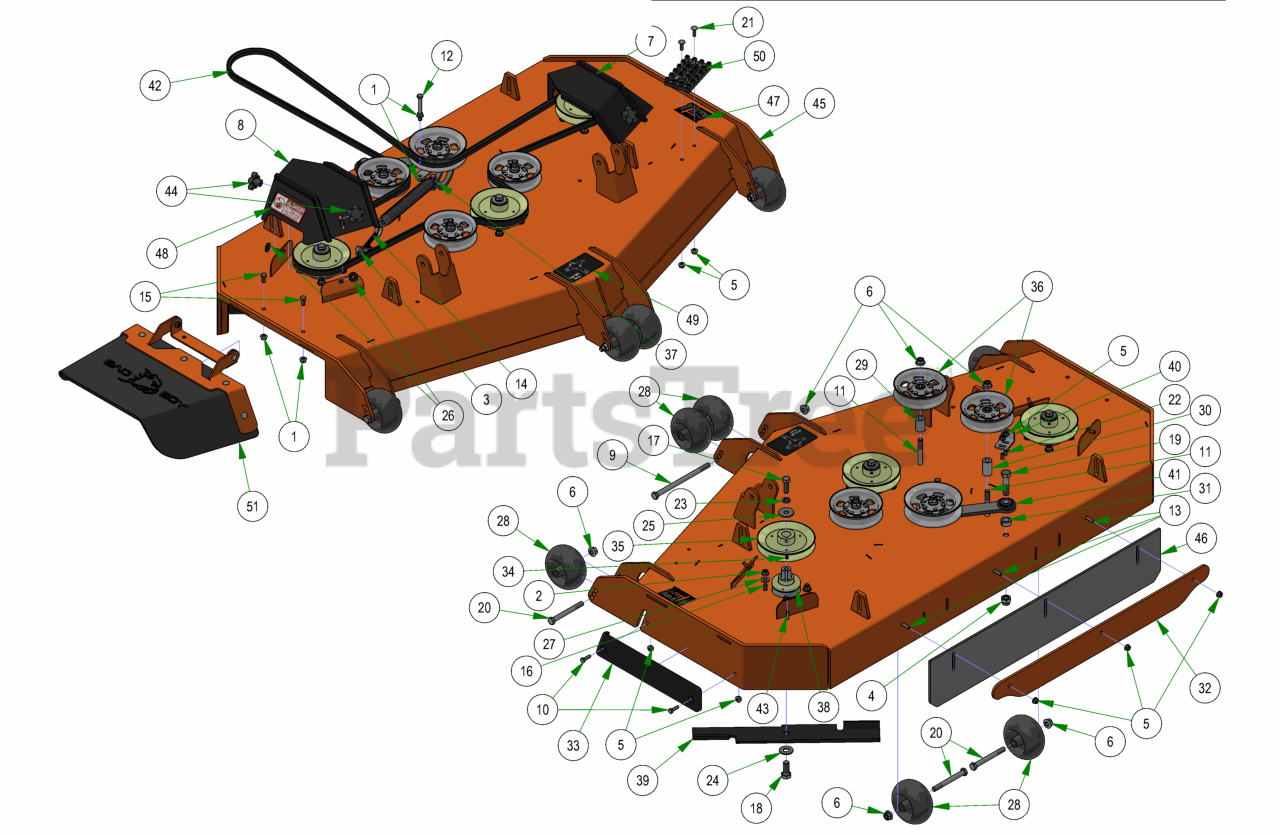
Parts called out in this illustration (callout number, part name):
1	3/8-16 HEX SERRATED FLANGE NUT HARD/ZINC
2	3/8-16 NYLON INSERT FLANGE LOCKNUT (GR.F) ZINC
3	3/8-16 HEX NUT ZINC
4	5/8-11 NYLON INSERT LOCKNUT ZINC
5	5/16-18 NYLON INSERT FLANGE LOCKNUT ZINC
6	1/2-13 NYLON INSERT FLANGE LOCKNUT ZINC
7	2019 61" Outlaw Gen2 Pulley Cover Left
8	2019 61" Outlaw Gen2 Pulley Cover Right
9	1/2-13 X 8 HEX CAP SCREW GR 5 ZINC
10	5/16-18 X 1 HEX CAP SCREW (GR.5) ZINC
11	1/2-13 X 3-1/2 HEX FLANGE BOLT (GR.8) ZINC
12	3/8-16 X 3 HEX CAP SCREW (GR.5) ZINC
13	5/16-18 X 1-1/4 CARRIAGE BOLT ZINC
14	4" 3/8-16 Eye Bolt
15	3/8-16 X 3/4 HEX CAP SCREW (GR.5) ZINC
16	3/8-16 X 1-1/2 HEX CAP SCREW (GR.5) ZINC
17	1/2-20 X 1-1/2 HEX CAP SCREW (GR.5) ZINC
18	5/8-18 X 1-1/2 HEX CAP SCREW (GR.8) ZINC YELLOW
19	5/8-11 X 2-1/2 HEX CAP SCREW (GR.5) ZINC
20	1/2-13 X 4-1/2 HEX CAP SCREW (GR.5) ZINC
21	5/16-18 X 1 CARRIAGE BOLT (GR.8) ZINC
22	5/16-18 X 7/8 CARRIAGE BOLT ZINC
23	1/2 SPLIT LOCKWASHER (GR.8) ZINC/YELLOW
24	5/8 USS FLAT WASHER (1-3/4" OD) GR.8 ZINC YELLOW
25	1/2 BELLEVILLE WASHER (1-5/8 OD X .140 THK) ZINC
26	.360 ID X .983 OD X .120 THICK FLAT WASHER NYLON BLACK
27	5/16 USS FLAT WASHER (7/8 OD) ZINC
28	2019 Deck Wheel
29	.502 ID X .750 OD X 1.500 Long Spacer
30	1 3/4" Pulley Spacer
31	5/8 SOLID SHAFT COLLAR (W/1 SET SCREW) ZINC
32	61 Bolt in Baffle Deck v2 Stripping Plate
33	REVISED TRIM BUMPER_20180226
34	5/16-24 X 1/4 SOCKET SET SCREW (CUP PT) PLAIN
35	6 1/4" Drive Pulley
36	5-3/4 Idler Pulley
37	2019 Outlaw Gen2 Deck Spring
38	OUTLAW SPINDLE ASSEMBLY
39	61 inch Fusion Blade
40	2019 Deck Eye Bolt Tab
41	2019 Rebel Rogue Deck Idler
43	1/4 X 1 SQ MACHINERY KEY 1018 STL PLN
44	5/16" Knob
45	2019 Sloped 61" Deck
46	R Series Rubber For Deck
47	61" Deck Decal
48	Danger Decal-Spindle/Discharge
49	2019 Rebel & Rogue Deck Belt Route Decal
50	Deck Step Assembly
51	2019 Outlaw Gen2 Chute Assembly
